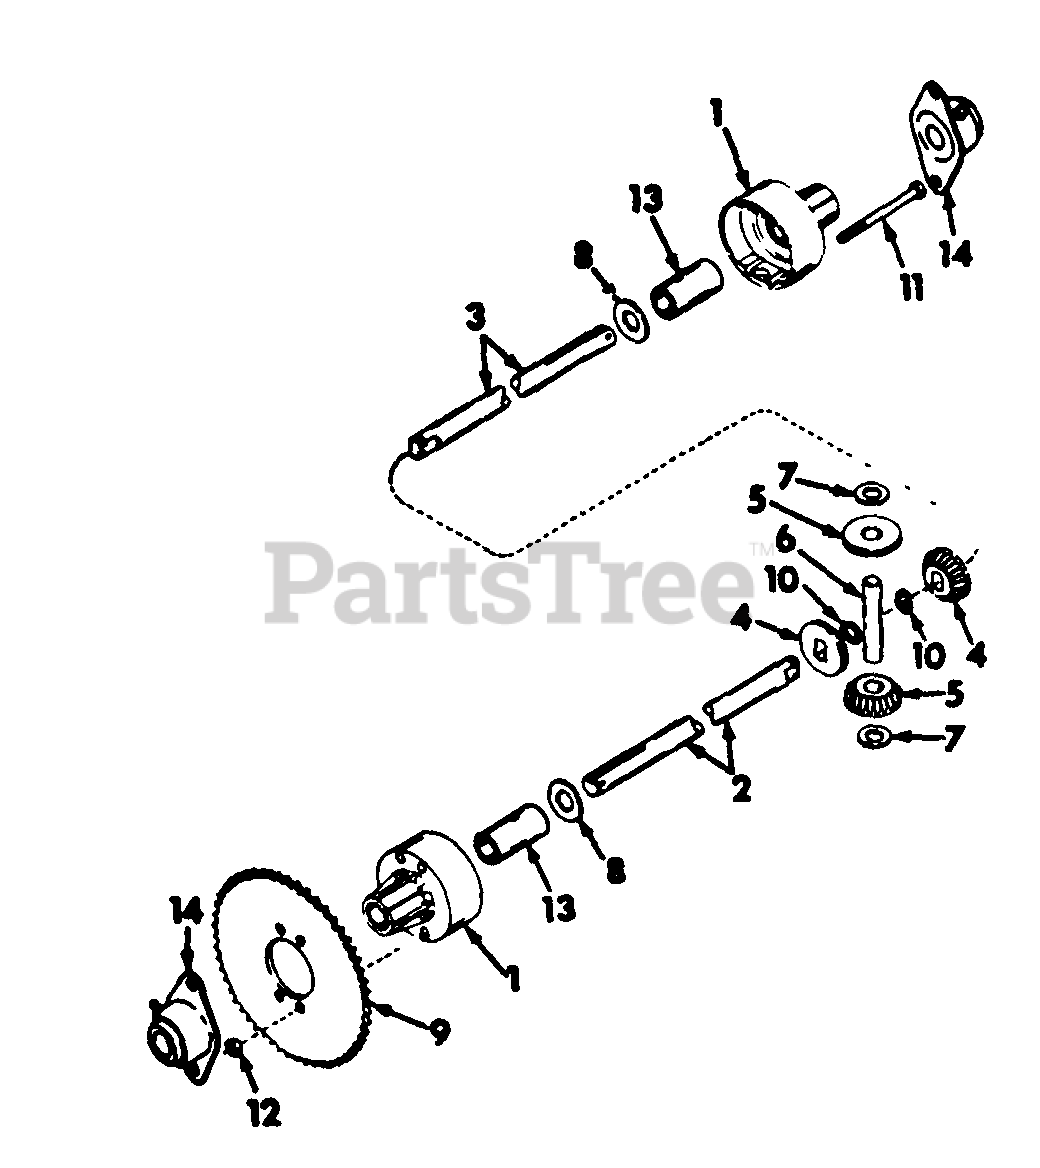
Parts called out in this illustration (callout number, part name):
1	HOUSING, DIFFERENTIAL CARRIER -SPROCKET SIDE-
1	HOUSING, DIFFERENTIAL CARRIER
4	GEAR, BEVEL -16 T
5	GEAR, PINION -16 T
7	WASHER, THRUST BRG RACE
9	SPROCKET, 45T
10	RING, .689 HVY EXT RET
11	SCREW, 5/16-18 SPECIAL
12	NUT, 5/16-18 LOCK
14	BEARING, REAR AXLE
